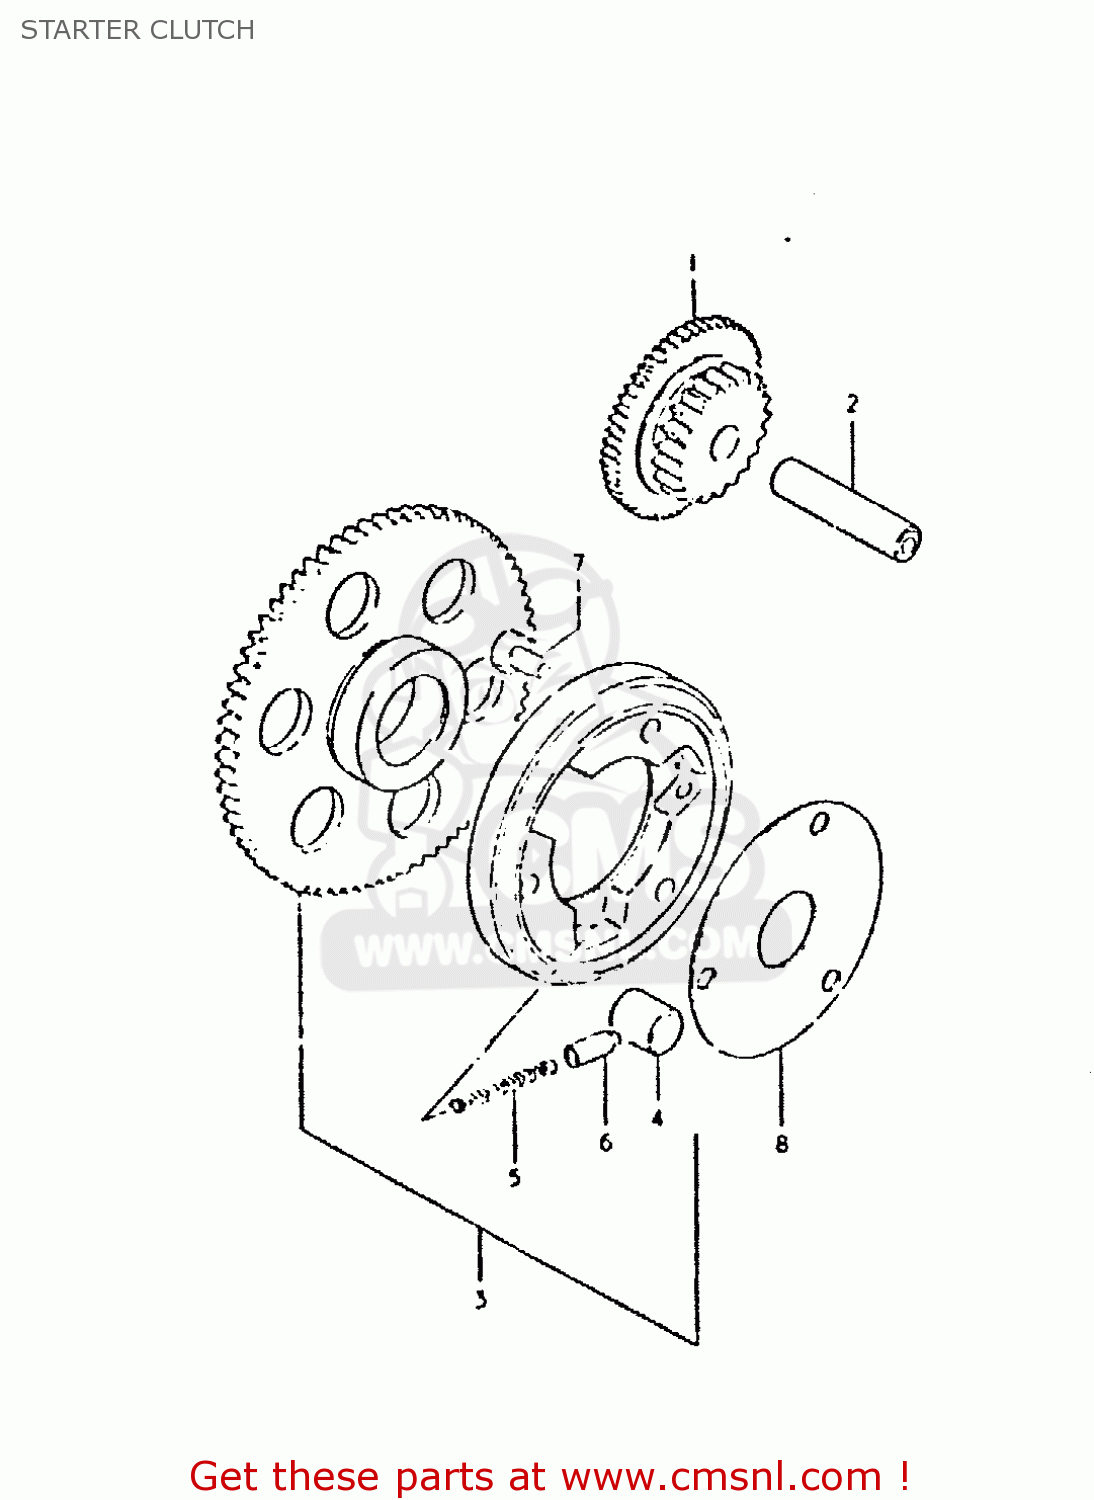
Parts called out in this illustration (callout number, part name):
1	GEAR,STARTER IDLE
2	PIN(7.4X13X56)
3	CLUTCH SET,STARTER
4	ROLLER(15X13)
5	SPRING
6	PIECE,PUSH
7	BOLT
8	SHIM,STARTER CLUTCH HUB
